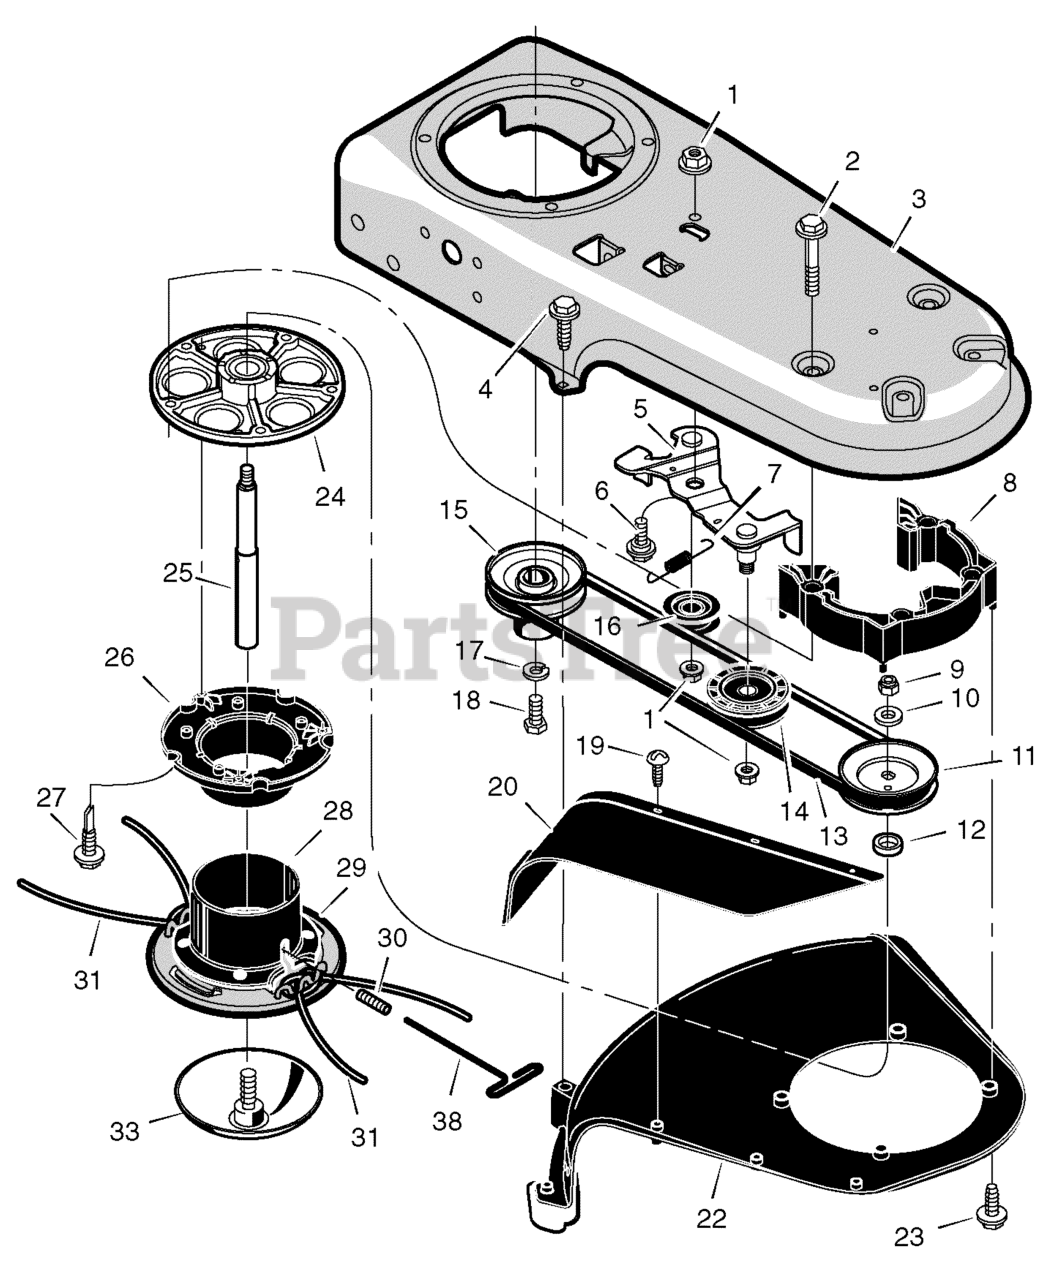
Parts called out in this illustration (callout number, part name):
1	Nut
5	Bracket, Idler Assembly
7	Spring, Extension
8	Spacer Assembly, Jackshaft
10	Washer, Flat
11	Pulley, Cutting Head
12	Spacer, Upper Pulley
13	Belt, Trimmer
14	"V" Pulley
15	Pulley, Engine
16	Pulley, Idler
17	Lockwasher
18	Bolt
20	Flap, Debris
22	Shield, Trimmer
24	Housing, Jackshaft
25	Shaft, Cutting Head
26	Wrap, Weed -Upper
28	Wrap, Weed -Lower
29	Assembly, Cutter Head & Wrap
30	Screw, Set
31	Line, Trimmer 0.155 X 21.25
33	Guide Assembly, Metal Height
38	Wrench, T-Handle
